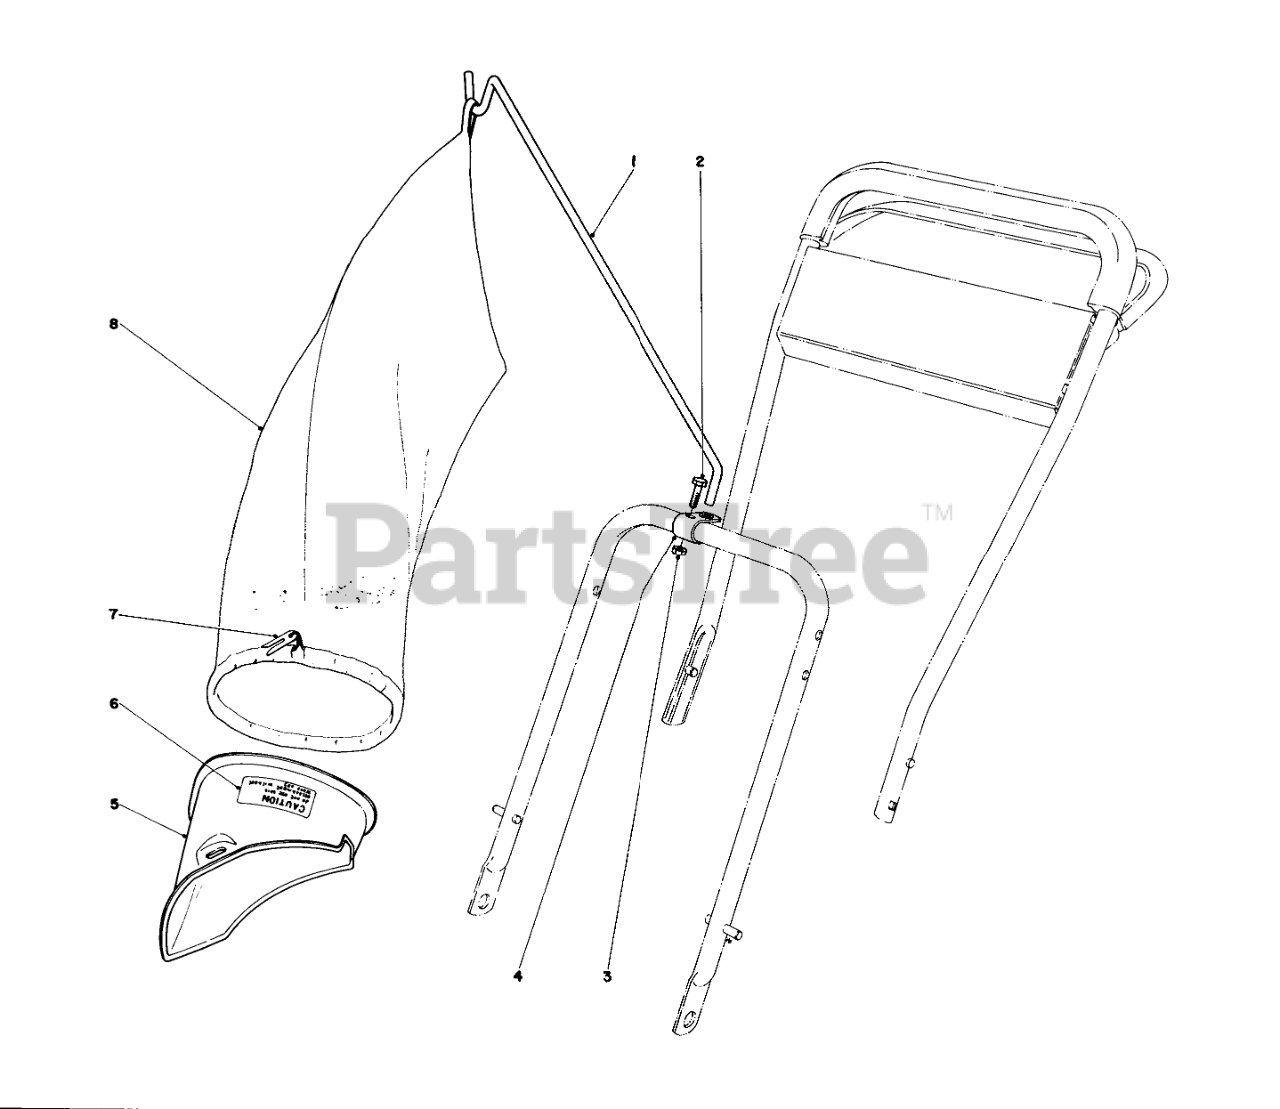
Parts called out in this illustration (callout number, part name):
1	Bag Rod
2	SCREW-HH
3	Nut
4	Adapter Bag Rod
5	Bag Chute (Incl. Ref. #6)
6	Decal
7	BAG CORD FASTENER
8	GRASS BAG
